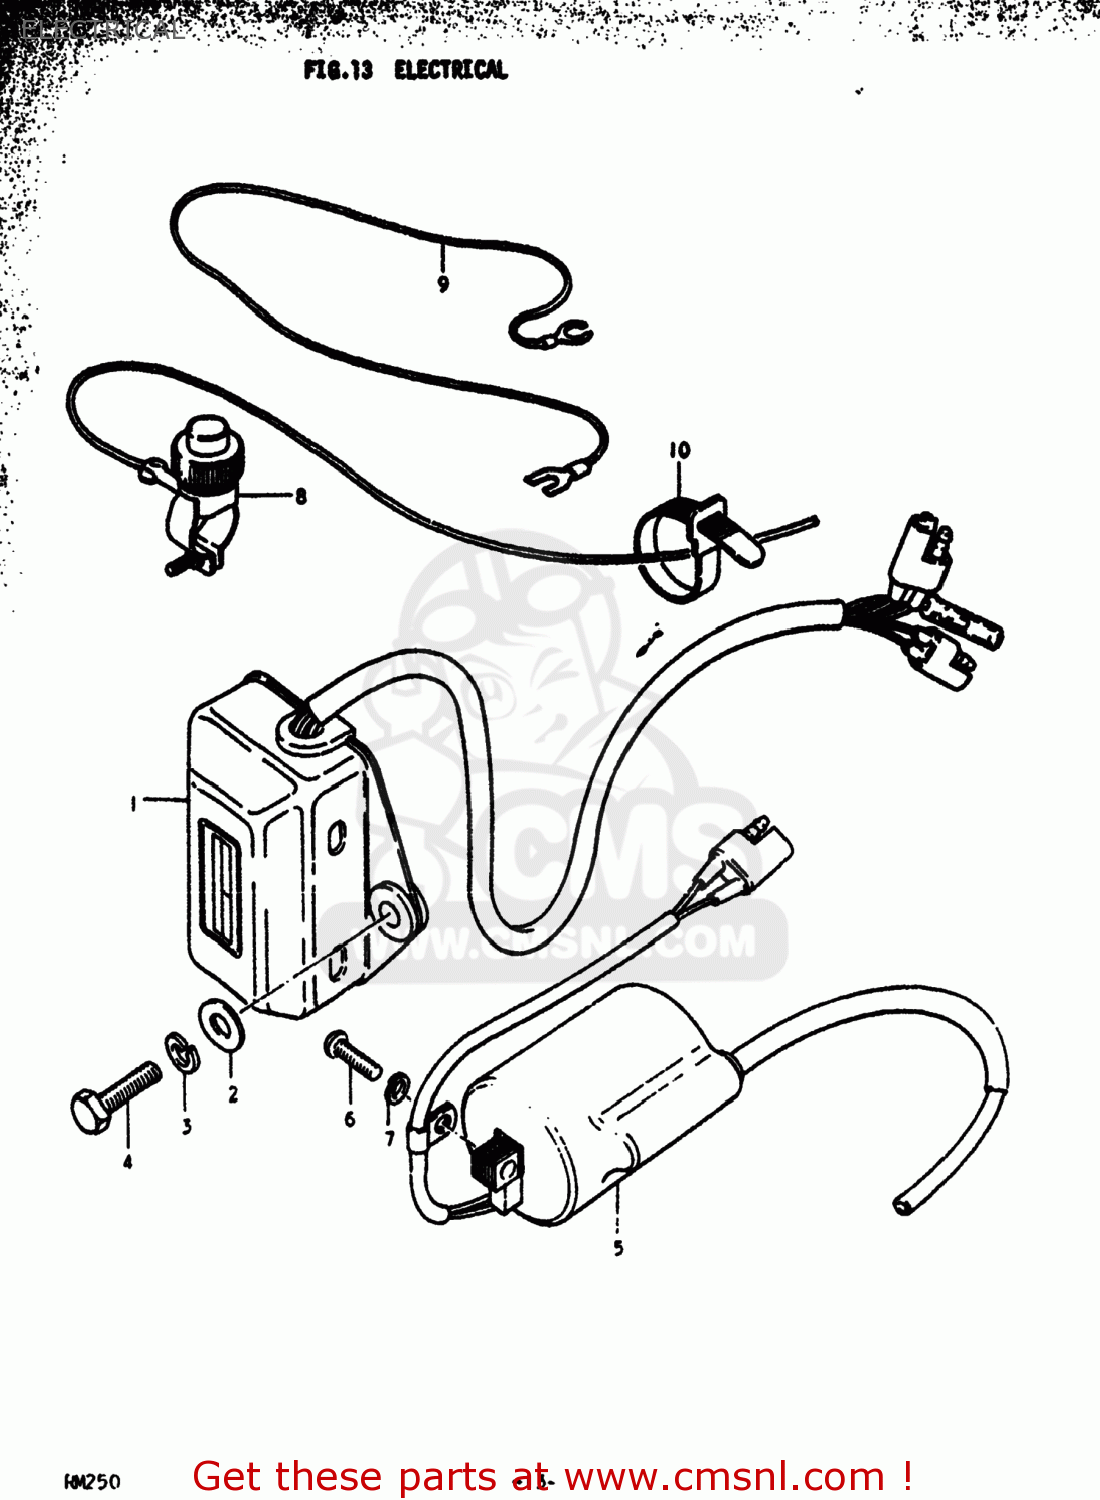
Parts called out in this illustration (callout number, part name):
1	CDI UNIT ASSEMBLY
2	WASHER(6.5X16X1.2)
3	LOCK WASHER
4	BOLT
5	COIL ASSY,IGNITION
6	SCREW 5X20
7	LOCK WASHER
8	SWITCH ASSEMBLY
9	WIRE,ENGINE STOP EARTH
10	CLAMP(L:120)
